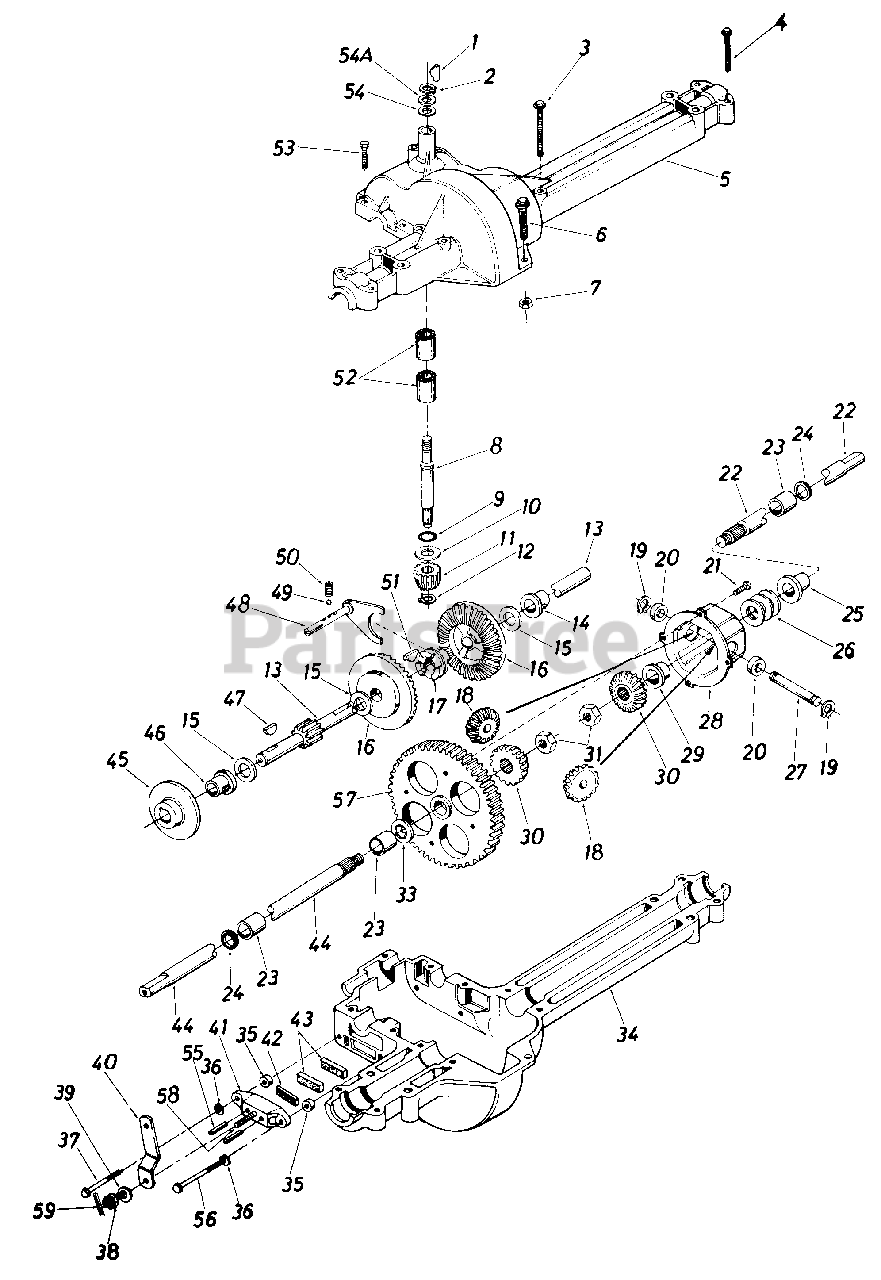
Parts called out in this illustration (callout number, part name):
1	#4 Hi-Pro Key 3/32 x 5/8" Dia.
2	Snap Ring .625" Shaft
3	Hex Bolt 1/4-20 x 1.75" Lg.
4	Hex Bolt 1/4-20 x 1.25" Lg.
5	Upper Housing
6	Hex Fl-Bolt 1/4-20 x .88" Lg.
7	Hex Nut 1/4-20 Thd.
8	Input Shaft
9	Square Seal 5/8" I.D.
10	Thrust Washer 5/8" I.D. x 1.25 O.D.
11	Pinion Input 14T
12	Retaining Ring 7/16" Ext.
13	Drive Shaft
14	Flange Brg. 5/8" I.D. x 3/4" Lg.*
15	Fl-Wash. 5/8" I.D. x 1.0" O.D. x .020" Thk.
16	Bevel Gear 42T
17	Clutch Collar
18	Miter Gear 15T
19	Snap Ring
20	Thrust Bearing 1/2" I.D. x 1.0" O.D.
21	Pan Head Scr. 1/4-20 x .50" Lg. w/Patch
22	Axle R.H. Kit
23	Sleeve Bearing 3/4" I.D. x 1.0" Lg.
24	Oil Seal 3/4" I.D.
25	Flange Bearing 3/4" I.D. x 15/16" Lg.
26	Fl-Wash. .760" I.D. x 1.49" O.D.
27	Cross Shaft
28	Differential Housing Ass'y.
30	Miter Gear
31	Retaining Ring
33	Fl-Wash. .760" I.D. x 1.49" O.D.
34	Lower Housing
35	Spacer .53" O.D. x 3/8" Lg.
36	L-Wash. 114" I.D.
37	Hex Bolt 1/4-20 x 1.50" Lg. Grade 5
38	Castle Nut 5/16-24 Thd.
39	Fl-Wash. .344" I.D. x .875" O.D.
40	Actuating Arm
41	Brake Yoke
42	Puck Plate
43	Brake Puck
44	Axle L.H. Kit
45	Brake Disc
46	Flange Bearing 5/8" I.D. x 15/16" Lg.
47	Woodruff Key 3/16 x 5/8 HT
48	Shift Fork Ass'y.
49	Ball Detent.250" Dia.
50	Spring Detent
51	#9 Hi-Pro Key 3/16" x 3/4" Dia. HT
52	Needle Brg. 5/8" I.D. x 1/2" Lg.
53	Hex Bolt 1/4-20 x 1.00" Lg.
54	Fl-Wash. 5/8" I.D. x .030
54A	Fl-Wash. 5/8" I .D. x .040
55	Actuating Pin 5/16" Dia.
56	Hex Bolt 1/4-20 x 1.50" Lg. Grade 5
57	Differential Gear 72T Ass'y. w/Bearing
58	Sq. Hd. Bolt 5/16-24 Thd.
59	Cotter Pin 3/32" Dia. x .50" Lg.
